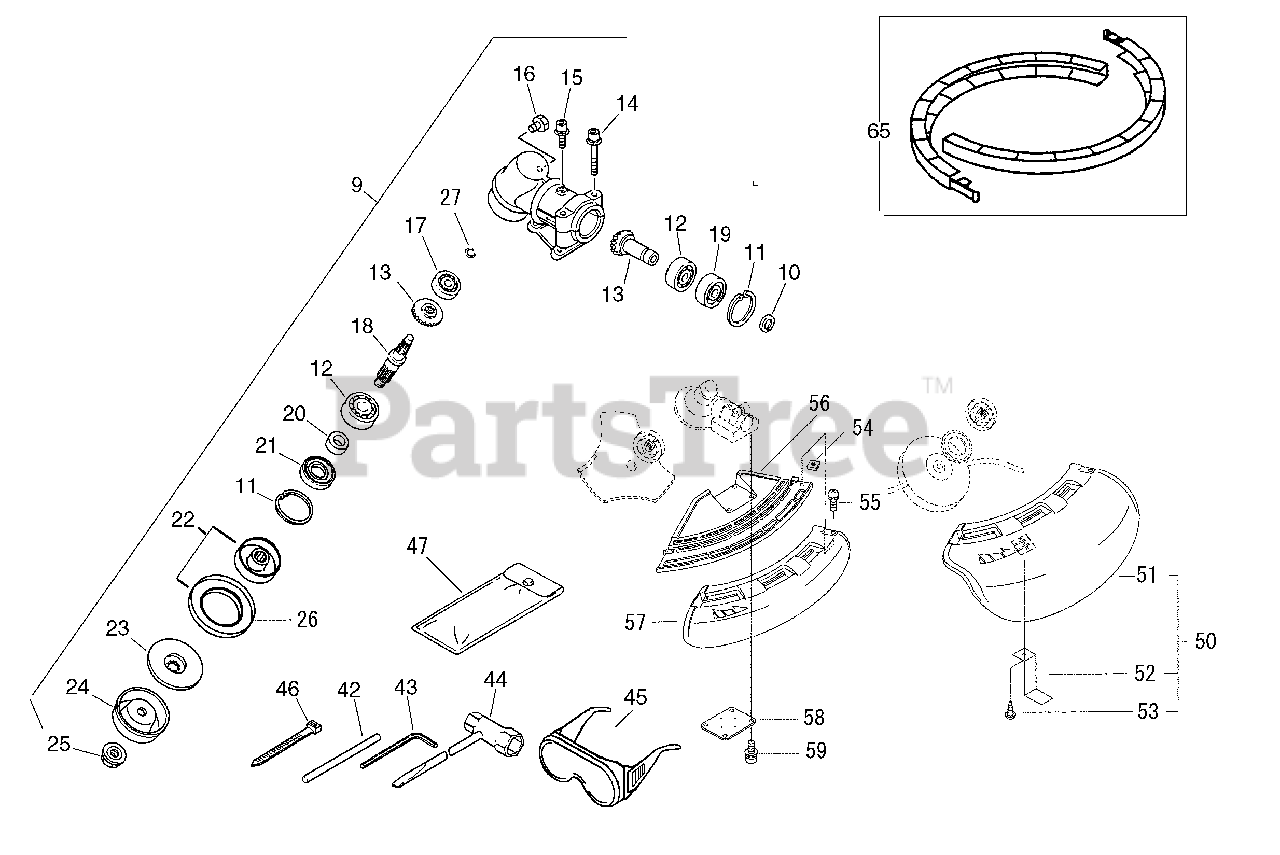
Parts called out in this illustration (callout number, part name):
9	GEAR CASE ASSY
10	RING, RETAINING - 15
11	RING, RETAINING - 35
12	BEARING, BALL - 6202
13	GEAR SET
14	SCREW - 5X35
15	SCREW - 5X12
16	BOLT - 8X8
17	BEARING, BALL - 6001
18	GEAR - SHAFT
19	BEARING, BALL - 6202Z
20	SPACER, OILSEAL
21	SEAL, OIL
22	BLADE ADAPTER KIT
23	ADAPTOR, BLADE - LOWER
24	PLATE,CUP
26	PLATE, CUP
27	RING, RETAINING - 12
42	ROD, LOCKING - 5X120mm
43	HEX KEY - 4mm
44	T-WRENCH - 17X19mm
45	GOGGLES
46	TIE, CABLE - SMALL
47	BAG, TOOL
50	DEBRIS SHIELD KIT - TRIMMER
51	SHIELD, DEBRIS - TRIMMER
52	KNIFE, TRIMMER LINE
53	SCREW - 5X12
54	NUT
55	SCREW - 5X18
56	ADAPTOR, DEBRIS SHIELD
57	SHIELD, DEBRIS - BLADE
58	BRACKET, SHIELD
59	SCREW - 5X25
65	COVER, BLADE
